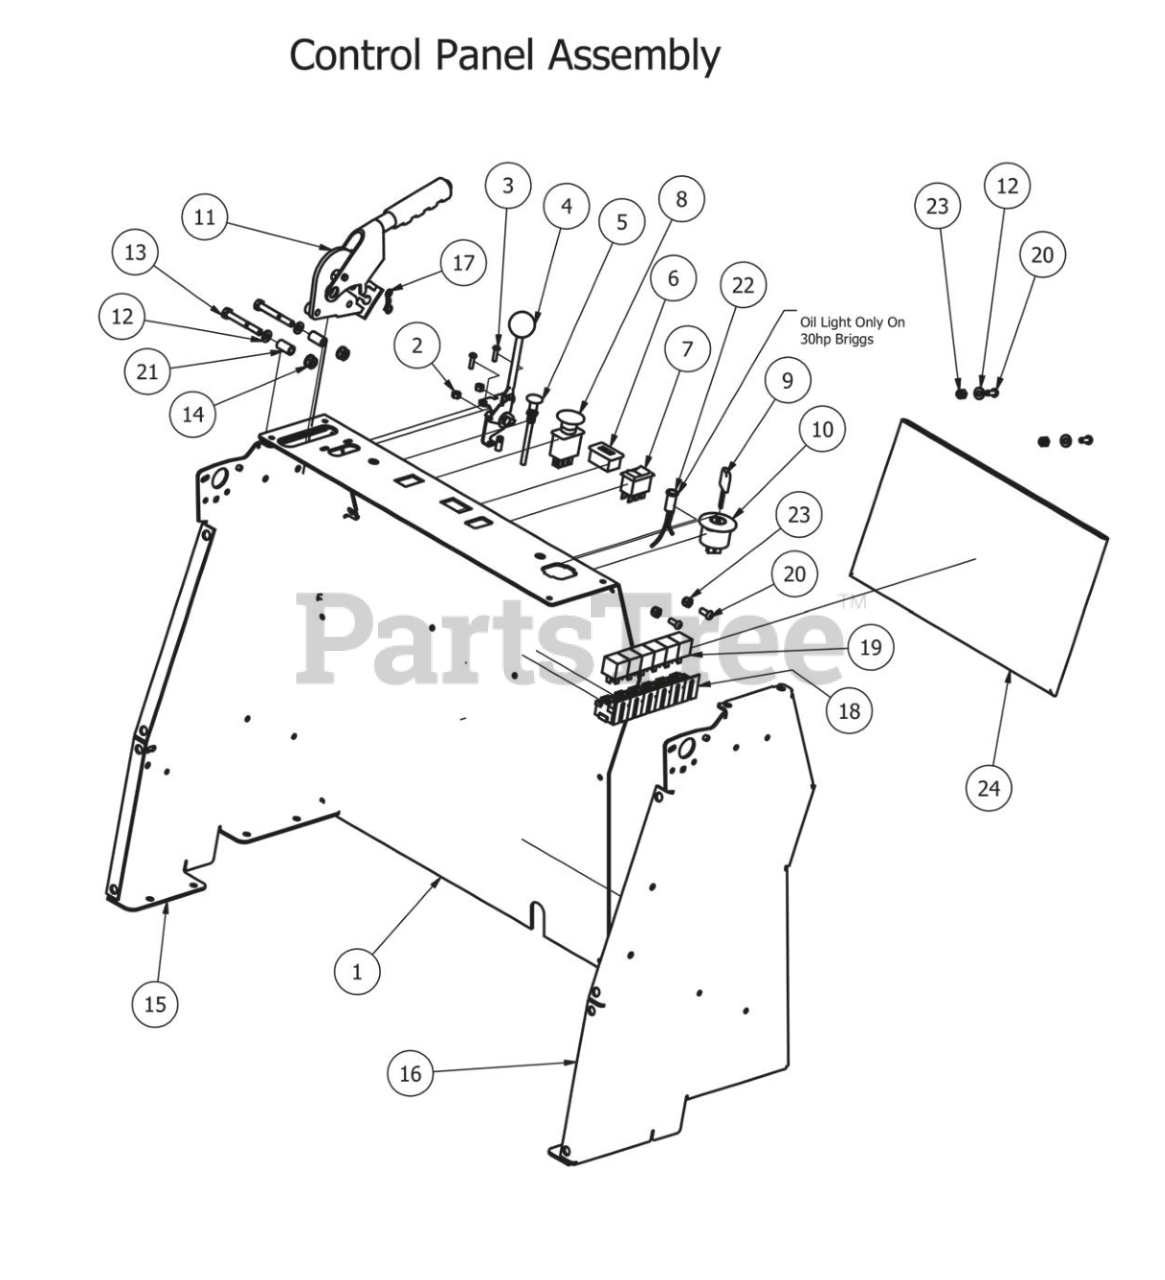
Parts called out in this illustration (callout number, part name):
1	Podium Front Panel
2	10-24 Nylon Insert Locknut
3	10-24 x 1 BS C/S 18-8 SS
4	Throttle-All Outlaws
6	Tachometer
7	Rocker Deck Lift Switch - 2011
8	PTO Engager
9	Ignition Key
10	Ignition Switch
11	Brake Handle- Stand On
12	1/4" Flat Washer
13	5/16" x 2 1/2" Bolt
14	5/16-18 Nylon Flange Nut
15	Podium Panel Left Side
16	Podium Panel Right Side
18	Wiring Harness- Stand on Models
19	Relay Terminal
20	1/4" x 5/8" BS C/S 18-8 SS
21	Brake/Latch Spacer-Stand On
23	1/4" Nylock Nut
24	Trash Collection Bag Bandit Stand On
